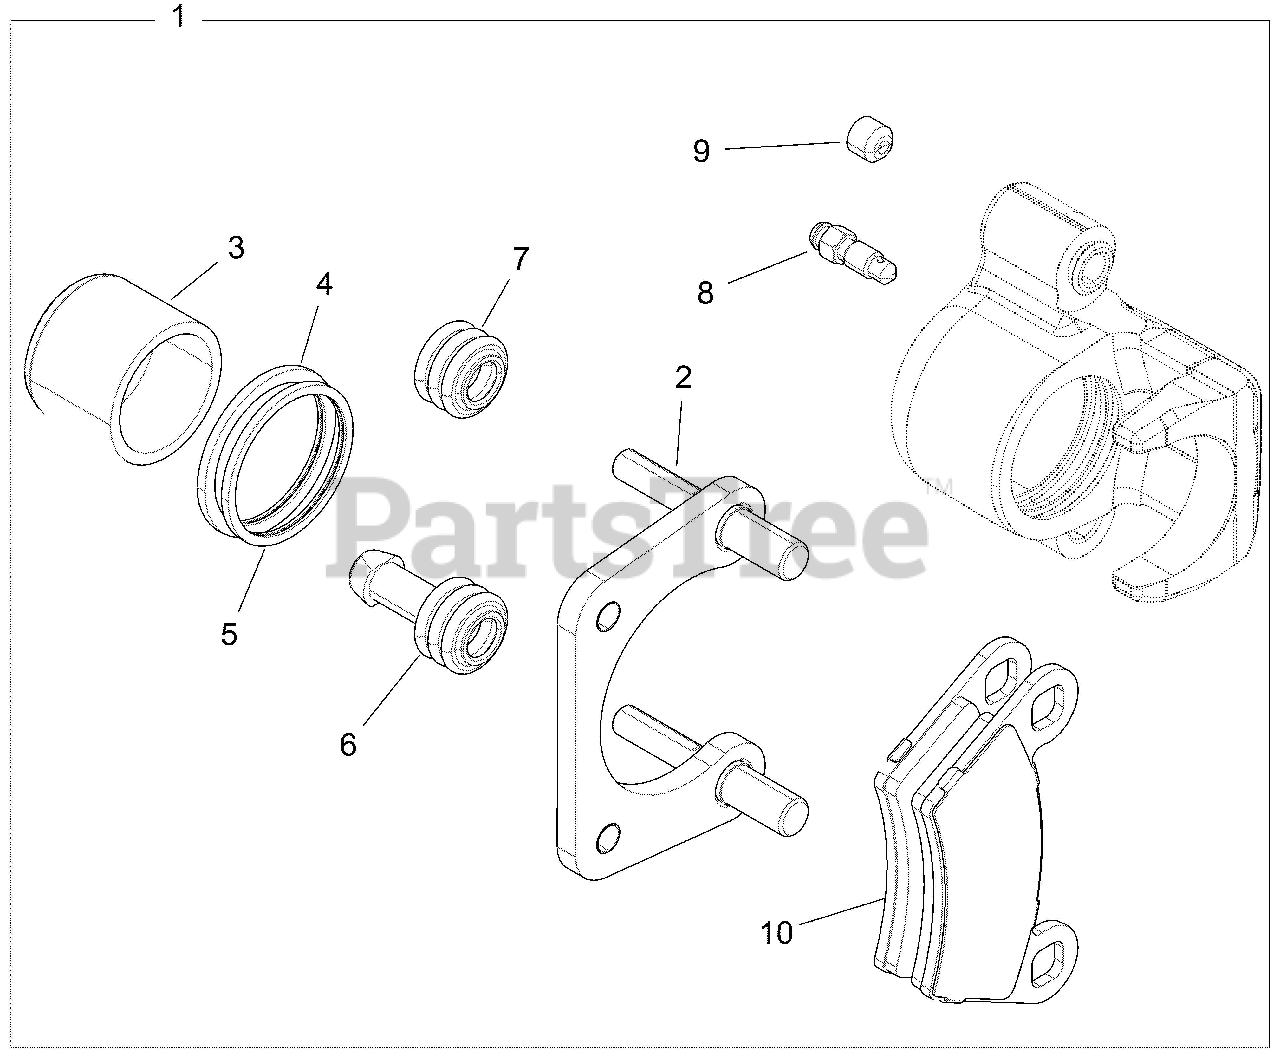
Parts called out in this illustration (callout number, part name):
1	ASM-CALIPER,BRAKE,1.5,LH,R MET
1	ASM-CALIPER,BRAKE,1.5,RH,R MET
2	ASM-CALIPER MOUNT,REAR,METRIC
3	PISTON-BRAKE,1.500
4	SEAL-CALIPER INNER,1.50"
5	SEAL-CALIPER,OUTER,1.50"
6	BOOT-PIN BUSHING
7	BOOT-PIN SEAL
8	SCR-M7X1.0,BLEEDER,OLIVE D
9	SCR-M10X1.0X8,SOC SET-OD
10	KIT-BRAKE PAD,ASM,1.5
